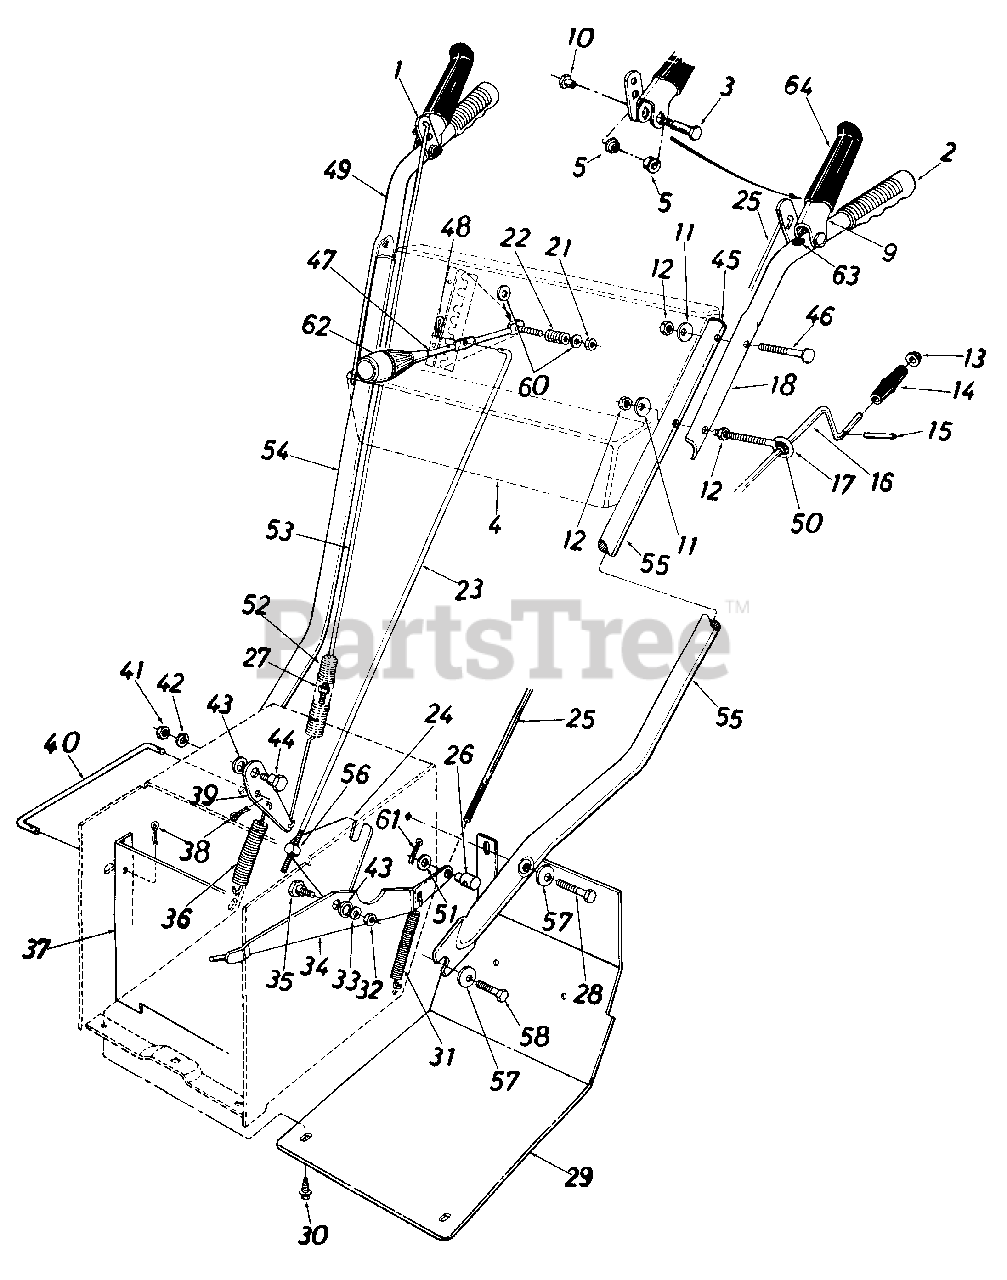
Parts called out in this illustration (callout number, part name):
1	Clutch Grip Ass'y.-R.H.
2	Grip-Red
3	Shoulder Bolt .374 Dia. x 1.375" Lg .
4	Handle Panel Ass'y.
5	Hex Flange Plastic Bearing .380" I.D.
9	Clutch Grip Ass'y.-L.H.
10	Shoulder Nut 1/4-20 Thd.
11	Bell-Wash. .34" I.D. x .88" O.D.
12	Hex Nut 5/16-18 Thd.
13	Push Nut 3/8" Rod
14	Knob 3/8" Rod
15	Roll Pin .12 Dia. x .63" Lg.
16	Chute Crank Ass'y. 39" Lg.
17	Eye Bolt 5/16-18 x 5.0" Lg.
18	Upper Handle-L.H. (Painted)
21	Hex Ins. Jam L-Nut 5/16-18 Thd.
22	Compression Spring .50n O.D. x .88" Lg.
23	Shifting Rod 5/16" x 32.50" Lg.
24	Shifting Linkage Bracket
25	Lockout Rod .214" Dia. x 36.0" Lg.
26	Adjustment Ferrule 1/4-20
27	Hex Ins. L-Nut 1/4-20 Thd.
28	Hex Bolt 3/8-16 x 2.00" Lg.
29	Frame Cover
30	Hex Wash. Self-Tap Scr. 1/4-20 x .50" Lg.
31	Extension Spring .38" O.D. x 3.25" Lg.
32	Hex Jam Nut 3/8-16 Thd.
33	L-Wash. 3/8" I.D.
34	Auger Clutch Bracket Ass'y.
35	Shld. Bolt .625" Dia. x .170
36	Extension Spring .75" O.D. x 4.31 " Lg.
37	Drive Pulley Support Brkt. Ass'y.
38	Cotter Pin 3/32" Dia. x .75" Lg.
39	Drive Clutch Bracket
40	Drive Clutch Rod
41	Hex Jam Nut 3/8-16 Thd.
42	L-Wash. 3/8" I.D.
43	Bell-Wash. .40" I.D. x 1.13" O.D.
44	Shld. Bolt .625" Dia. x .170
45	Plastic Plug
46	Carriage Bolt 5/16-18 x 2.0n Lg.
47	Shift Handle
48	Int. Cotter Pin 5/16" Dia.
50	Plastic Bushing
51	Fl-Wash. .344" I.D. x .62" O.D.
52	Extension Spring .75" O.D. x 5.00" Lg.
53	Lockout Rod .214" Dia. x 32" Lg.
54	Lower Handle-R.H. (Painted)
55	Lower Handle-L.H. (Painted)
56	Adjustment Ferrule
57	Bell-Wash. .40" I.D. x .88" O.D.
58	Hex Wash. Self-Tap Scr. 3/8-16 x .75" Lg.
60	Fl-Wash. .344" I.D. x .62" O.D.
61	Cotter Pin 3/32" Dia.
63	Push Cap
64	Black Vinyl Grip
